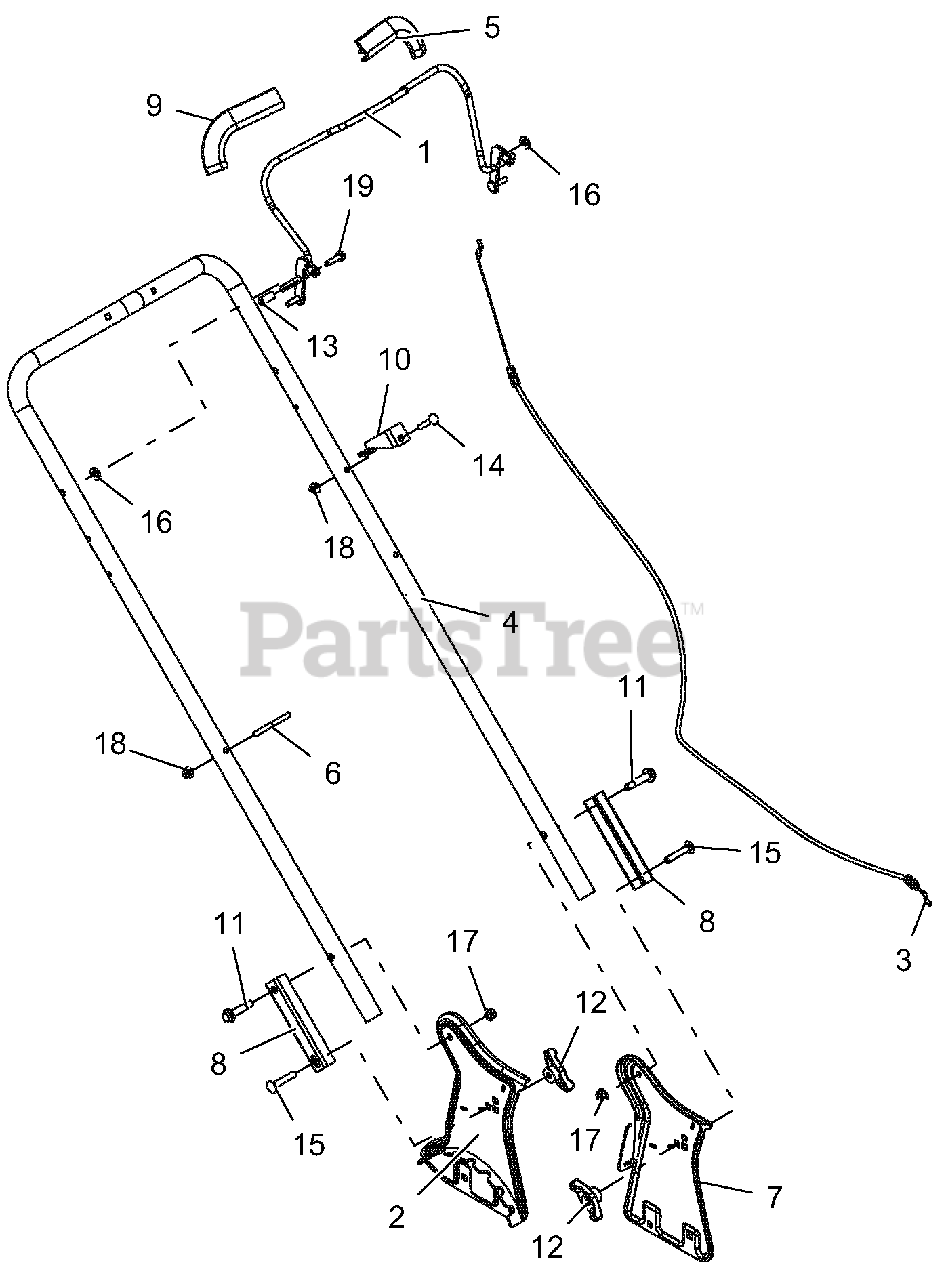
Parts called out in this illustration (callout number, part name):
1	WLDMT, OPC BAIL
2	SUPPORT, RH HANDLBAR
3	CABLE, OPC
4	HANDLEBAR, LM
5	GUARD, FINGER - LH
6	HOLDER, RECOIL CORD
7	SUPPORT, LH HANDLEBAR
8	BRKT, HANDLEBAR FIXED ADJUST
9	HAND GRIP W/ DECAL
10	BRKT, CABLE ANCHOR - LM PUSH
11	BLT-SHLDR, .50X1.15X.312-18GR5
12	KNOB,WING .31-18 UNC NYL/TALC
13	CAP, VINYL, .25 ID
14	@BLT-RDHDSQNK .25-20X1.50 G5YZ
15	@BLT-RDHDSQNK .31-18X1.75 G5YZ
16	@WSHR-FL-STL.344X.688X.065YWZC
17	@NUT-LK-TOP-FLG .31-18 YWZC
18	@NUT-LK-TOP-FLG .25-20 YWZC
19	@SCR-TAP .25-20X1.00 HWH TR YZ
